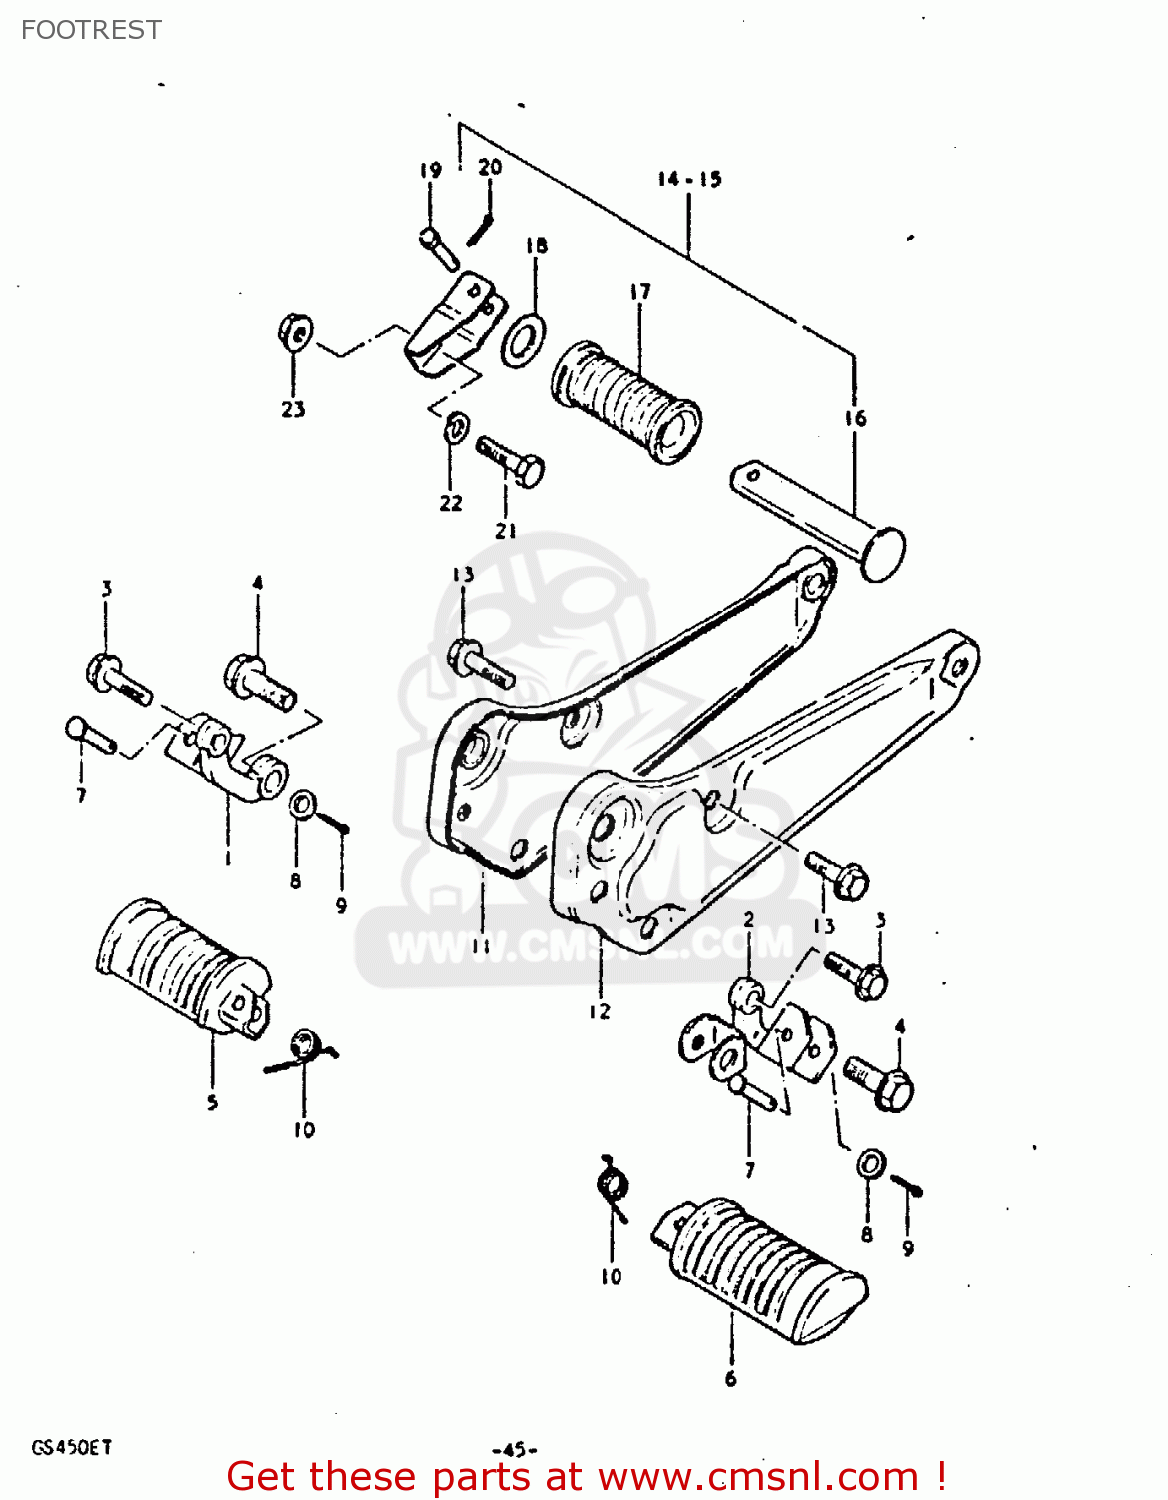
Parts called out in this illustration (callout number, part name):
1	BAR,FRONT FOOTREST,RIGHT
2	BAR,FRONT FOOTREST,LEFT
3	BOLT
4	BOLT
5	RUBBER,FRONT FOOTREST
6	FOOTREST
7	PIN
8	WASHER
9	PIN
10	SPRING
11	BRACKET
12	BRACKET
13	BOLT
14	FOOTREST ASSEMBLY,REAR
15	FOOTREST ASSEMBLY,PILLION
16	BAR,PILLION FOOTREST
17	RUBBER,PILLION FOOTREST
18	WASHER (19.5X32X2)
19	PIN
20	PIN
21	BOLT,M10X1.25X
22	LOCK WASHER
23	NUT
